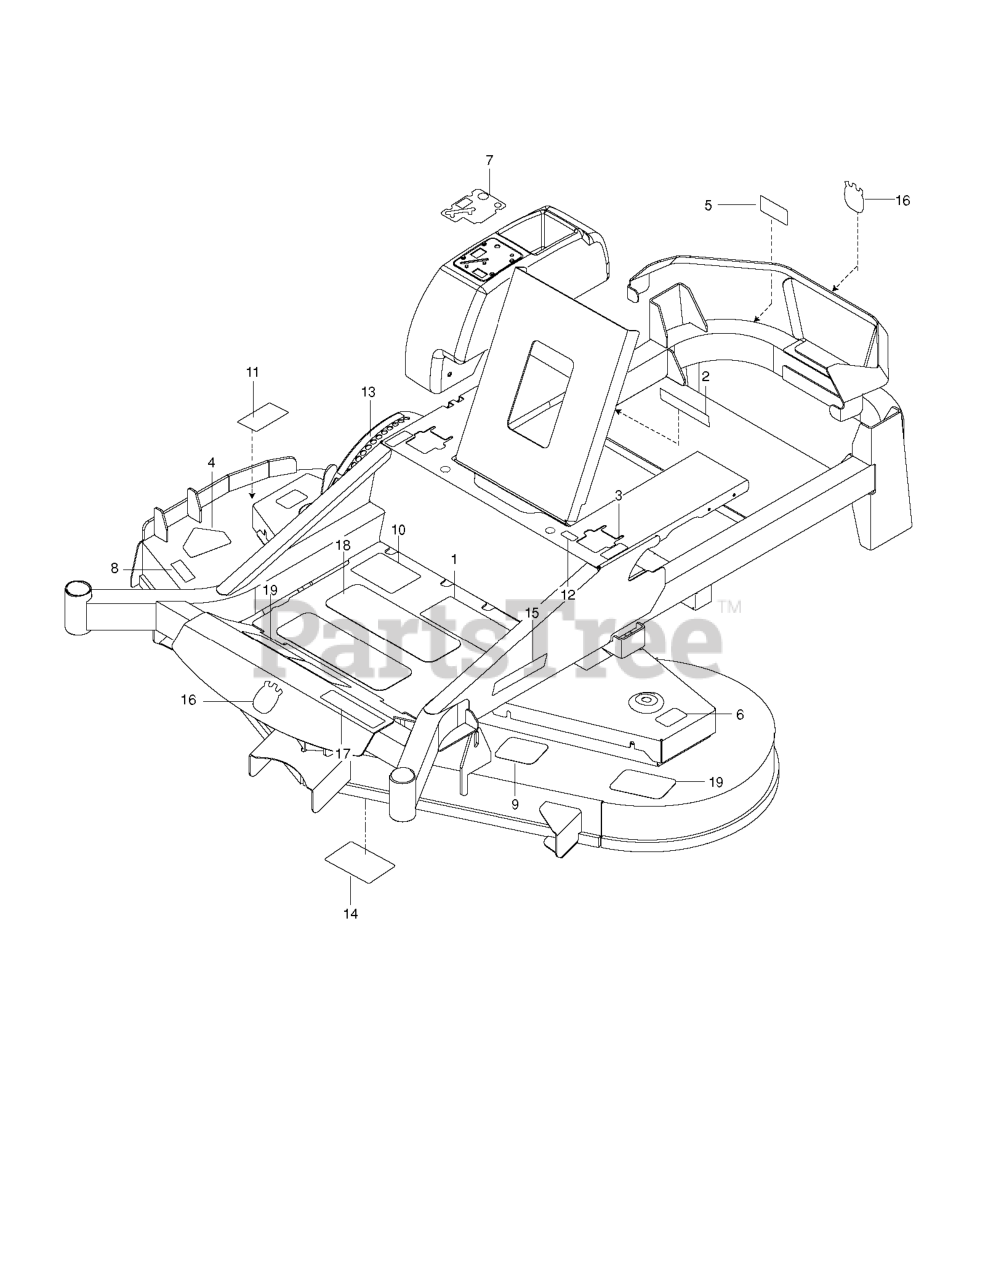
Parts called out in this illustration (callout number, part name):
1	DECAL, WARNING
2	EURO DECAL-BATTERY WARNIN6
3	DECAL, MOTION CONTROL
4	DECAL, DECK DEFLECTOR, WARNING
5	DECAL, BELT DRIVE
6	DECAL.DECK.6MIL.EURO.NOSTEP
7	DECAL, CONSOLE HUS
8	DECAL, EURO SEVERING
9	DECAL, BELT ROUTING
10	DECAL.ZTR.STRTNGINST.REMOTECHK
11	DECAL.DECK.6MIL./DEF.SHLD.WARN
12	DECAL, F.S.T.
13	DECAL, HEIGHT ADJUST
14	DECAL, SERVICE
15	RP.DECAL.BADGE.170MM.TEXTLOGO
16	DECAL.AUGER.HUSQ.CROWN.SNOW
17	DECAL.MZ52LE.HUSQ
18	ANTI-SKID PAD
